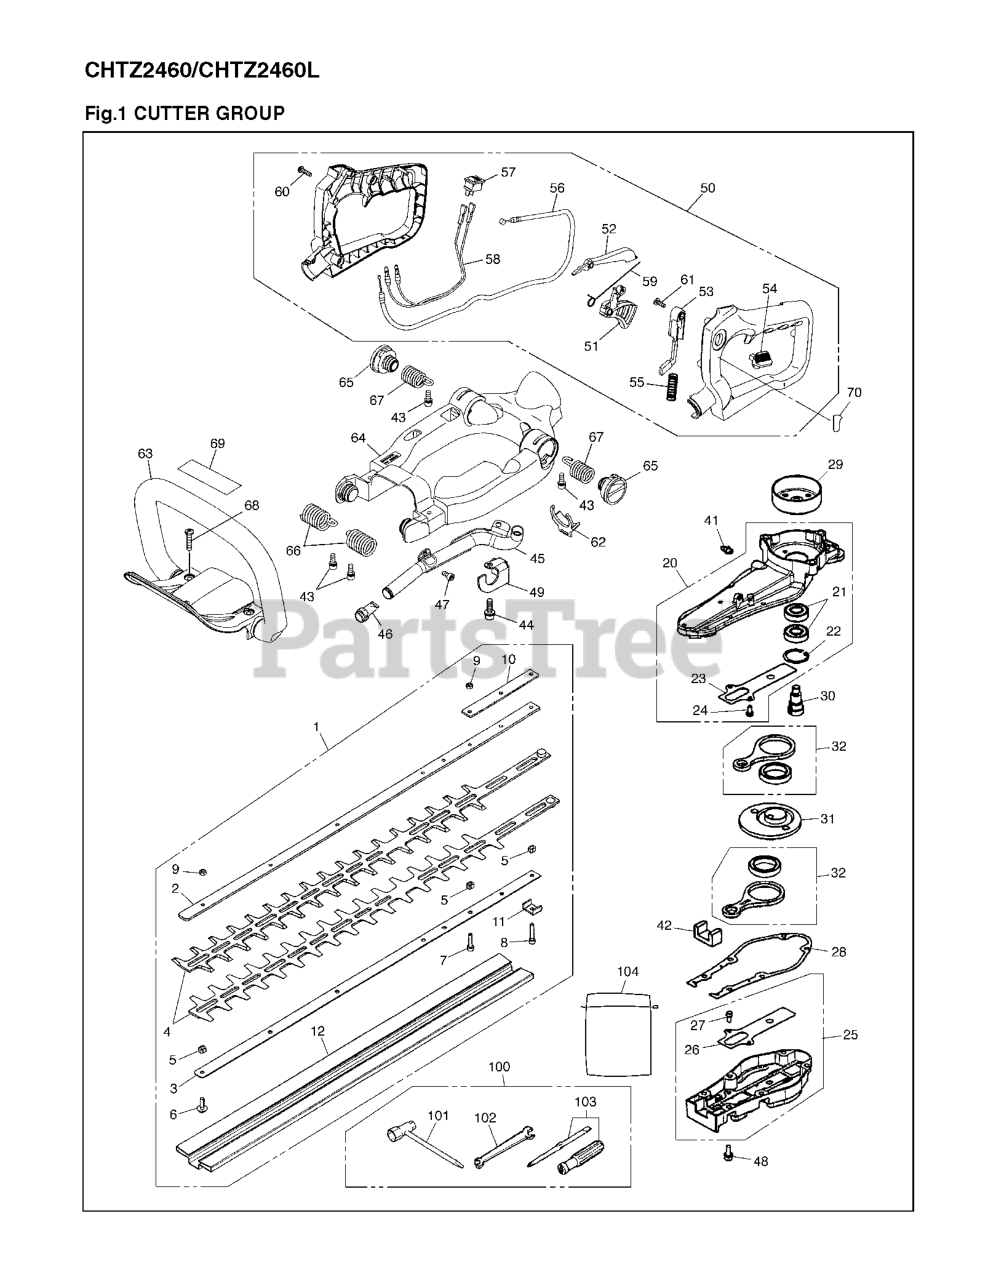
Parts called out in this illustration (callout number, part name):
2	PLATE
3	PLATE, LOWER
4	BLADE (24")
5	SPACER
12	BLADE COVER
20	GEAR HOUSING COMP
24	BOLT
25	CAP COMP
27	BOLT
30	GEAR DRIVE
31	GEAR DRIVE
32	ROD ASSY
45	EXHAUST PIPE
46	ARRESTER
50	HANDLE-REAR-A
51	LEVER.THROTTLE
56	CABLE COMP
61	SCREW
63	HANDLE F
66	SPRING F
67	SPRING R
100	TOOL KIT ASSY
